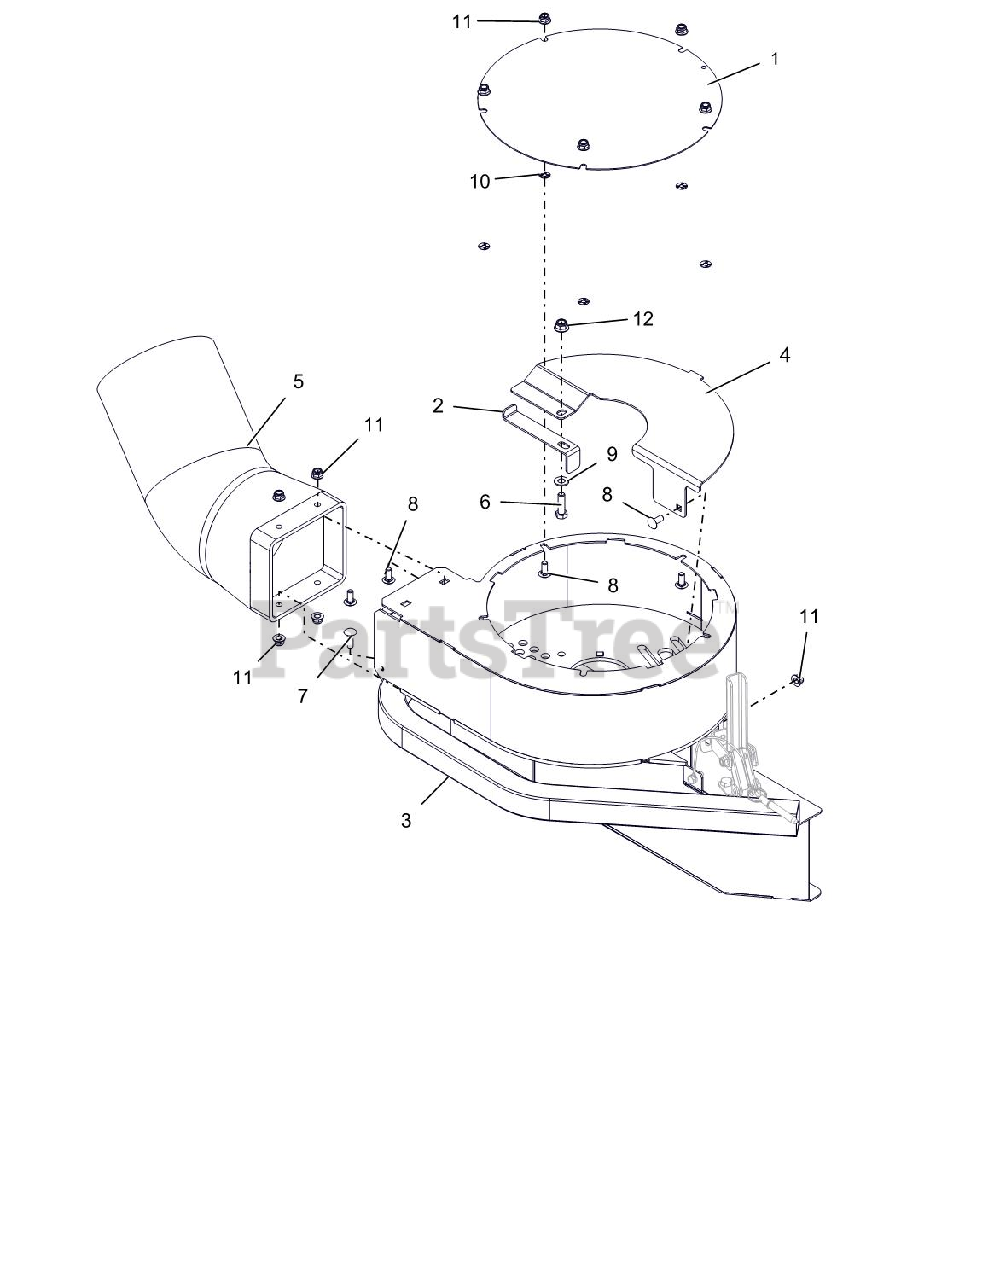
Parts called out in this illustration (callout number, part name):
1	COVER, BLOWER-RED
2	FINGER - BELT
3	COMM BAGGER BLOWER WLDMT - RED
4	COVER, BOTTOM
5	ADAPTER-HOSE 52/60"
6	@BLT-HEX .38-16X1.25 GR5 YWZC
7	@BLT-RHDSSQNK .31-18X1.00 G5YZ
8	@BLT-RHDSSQNK .31-18X.75 G5YZ
9	@WSHR-FL-STL.406X.812X.065 YWZ
10	NUT-PUSH .312
11	@NUT-LK-NYL-FLG .31-18 YWZC
12	@NUT-LK-NYL-FLG .38-16 YWZC
